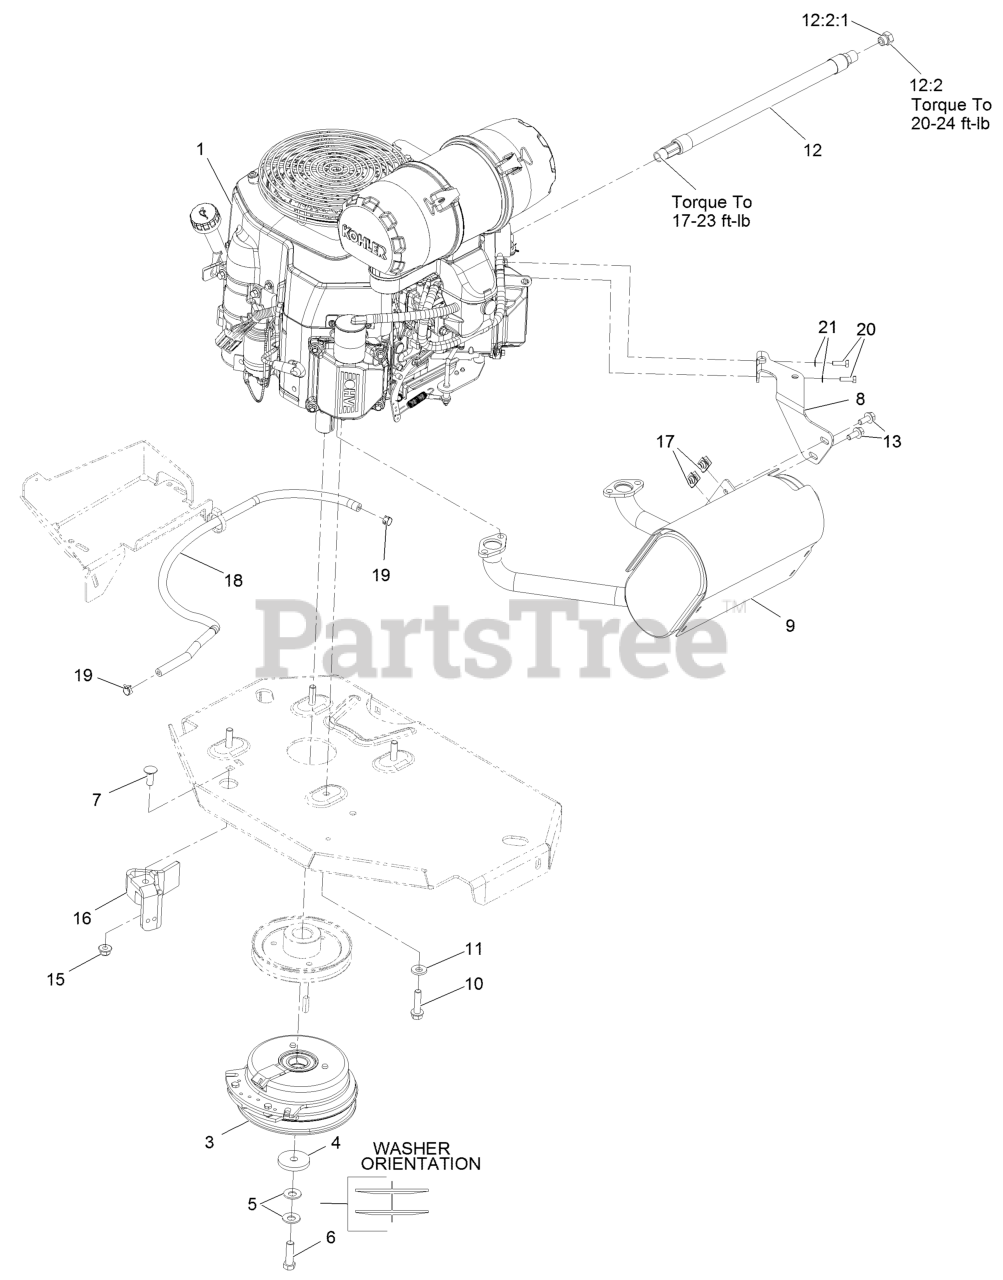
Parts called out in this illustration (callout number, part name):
1	Engine-Kohler
3	CLUTCH KIT
4	WASHER-CLUTCH
5	WASHER-SPRING
6	SCREW-HH 7/16-20 X 1 1/2 W/LOCTITE
7	SCREW-CARR
8	MUFFLER BRACKET KIT
10	SCREW-HWH
11	WASHER-BELLEVILLE
12	OIL DRAIN HOSE ASM
12:2	PLUG-HH
12:2:1	O-RING
13	SCREW-HHF
15	NUT-HF, NI
16	CLUTCH-ANCHOR
18	HOSE-FUEL
19	CLAMP-HOSE
20	SCREW-HH M6-1 X 20Mm W/Patch
21	WASHER-SPRING
